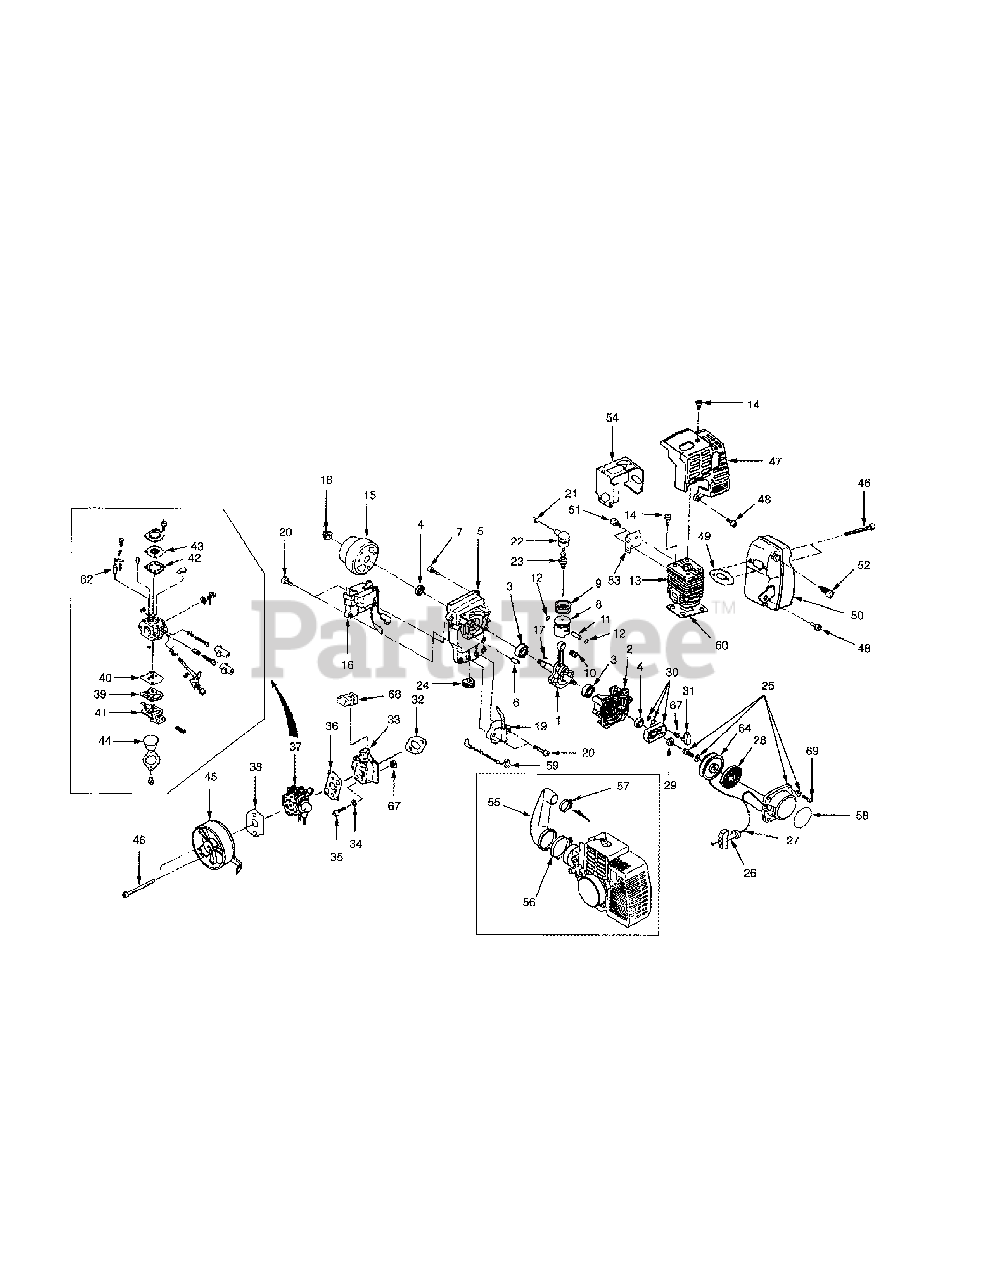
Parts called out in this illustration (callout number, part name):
2	Crankcase Assembly
3	Bearing, Ball, 6202
5	Crankcase Assembly
8	Piston Assembly
9	Ring, Piston
10	Bearing, Needle
12	Clip, Piston Pin
15	Flywheel, Magneto
19	Coil Assembly, Ignition
23	Spark Plug
25	Recoil Assembly
26	Knob, Starter
27	Rope, Starter
28	Spring, Spiral
30	Pulley Assembly, Starter
32	Gasket, Insulator
34	Washer
36	Gasket
37	Carburetor Assembly
38	Gasket
40	Diaphragm, Pump
41	Body, Pump
43	Diaphragm, Metering
44	Rubber
47	Cowling, Cylinder
49	Gasket, Muffler
53	Plate, Baffle
55	Elbow, Intake
59	Harness, Wire
60	Gasket, Cylinder
62	Valve, Float
